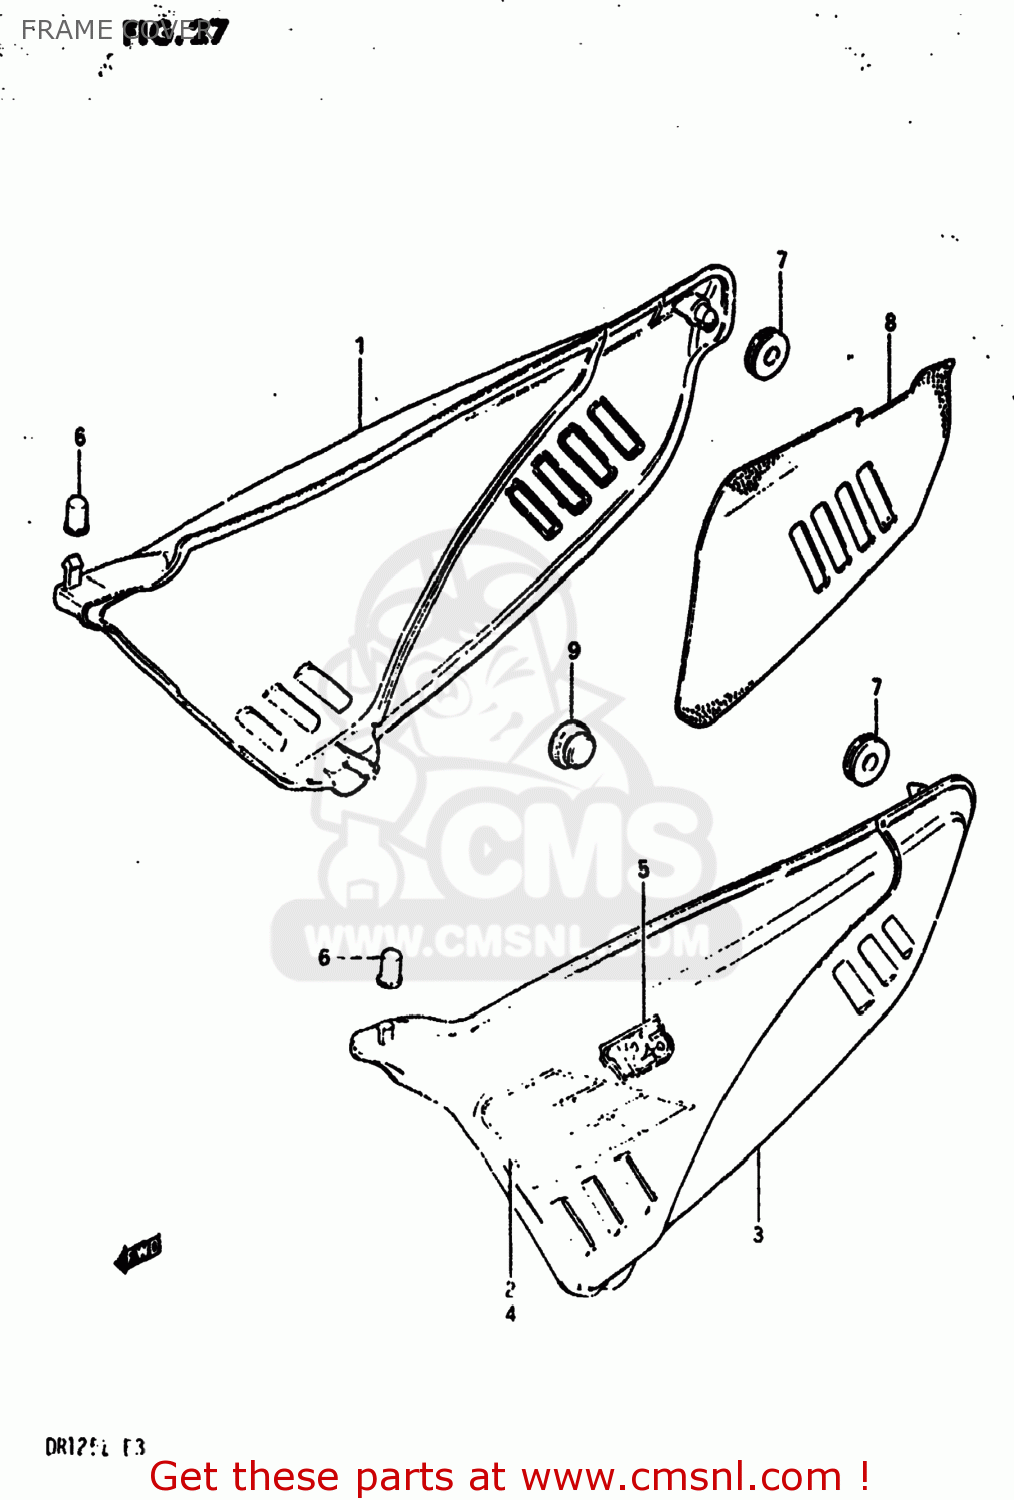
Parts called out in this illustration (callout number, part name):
1	COVER,FRAME,RIGHT
2	TAPE SET,FRAME COVER
3	COVER,FRAME,LEFT
4	TAPE SET,FRAME COVER
5	EMBLEM
6	CUSHION
7	CUSHION
8	HEAT SHIELD,FRAME COVER
9	CUSHION
